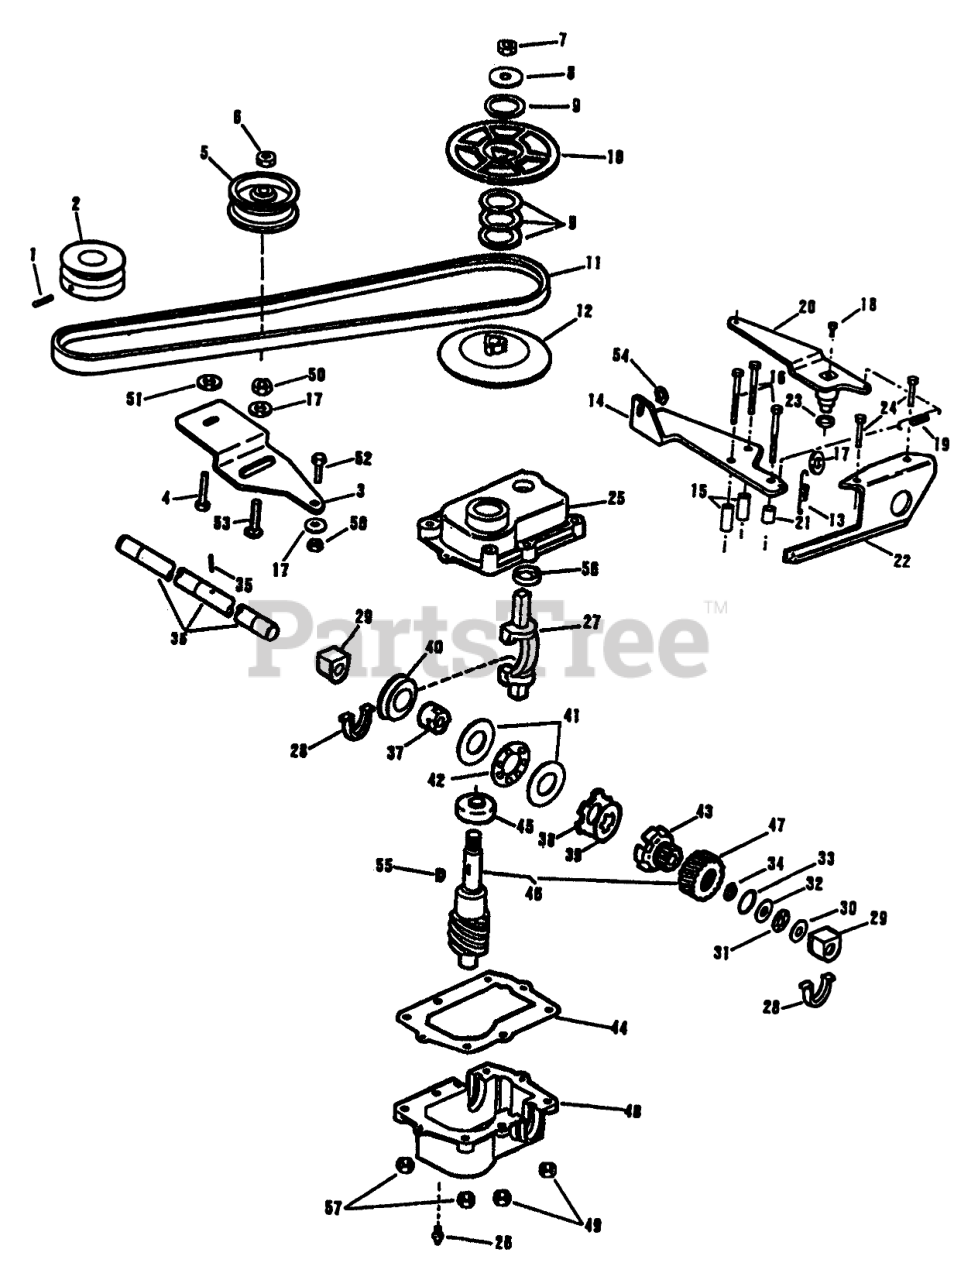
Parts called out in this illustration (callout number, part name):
1	SET SCREW F
2	PULLEY F
3	IDLER & BRACKET AY (12)
4	SCREW
5	PULLEY IDLER NHI
6	NUT-JAM, LOCKING
7	NUT
8	WASHER
9	WASHER
10	PULLEY UPPER PL
11	V-BELT F
12	PULLEY LOWER PL
13	SPRING EXTEN D&B
14	CONDUIT ANCHOR BRKT
15	SPACER
16	SCREW
17	WASHER S
18	SCREW SEMS SM
19	SPRING
20	SHIFT ARM HUB STA
21	SPACER
22	TENSIONER BRKT
23	O-RING
24	SCREW
25	Gearcase-Upper
26	PLUG
27	FORK SHIFT
28	PACKING MICH RUB
29	BEARING & SEAL AY (12)
30	THRUST WASHER
31	Bearing-Thrust
32	WASHER-THRUST
33	WASHER
34	RET RING
35	PIN DRIVE LOCK
36	SHAFT DRIVE
37	SLEEVE ALLEGHENY
38	Driver Plate
39	Driven Plate
40	Collar
41	Thrust Washer
42	Bearing
43	DRIVER BROCKWAY
44	GASKET HOOSIER
45	BEARING
46	WORM WHEEL & SHAFT
47	WORM WHEEL
48	GEAR CASE
49	LOCKNUT E
50	NUT-LOCK F
51	WASHER
52	Screw
53	Bolt
54	RET. RING
55	KEY GALGER
56	GUIDE ELCO
57	LOCKNUT E
